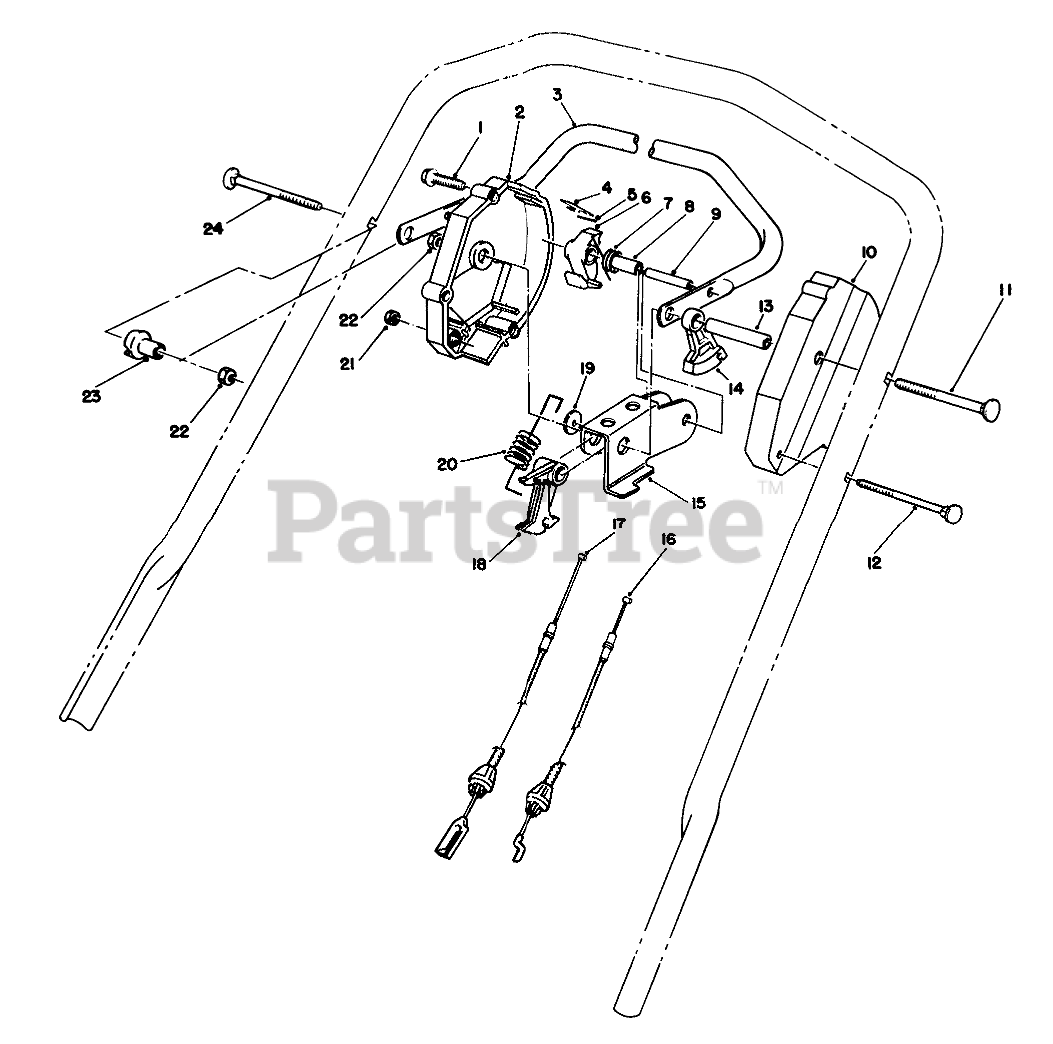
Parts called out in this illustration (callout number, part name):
1	SCREW-HWHTF
2	Housing-Control
3	Bar-Control
4	SPRING-LEAF
5	PIN-INSERT
6	HOOK-CONTROL
7	SPRING-TORSION
8	SPACER
9	PIN-ROLL, SLOTTED
10	HOUSING-CONTROL, LH
11	Screw-Handle
12	HANDLE SCREW
13	TUBING-SPACER
14	LEVER-TRACTION
15	ROCKER
16	Cable-Traction
17	Cable-BBC
18	LEVER-CABLE
19	WASHER-NYLON
20	SPRING-DETENT
21	NUT-HEX
22	NUT-LOCK, NI
23	SPACER-SUPPORT
24	SCREW-HANDLE
